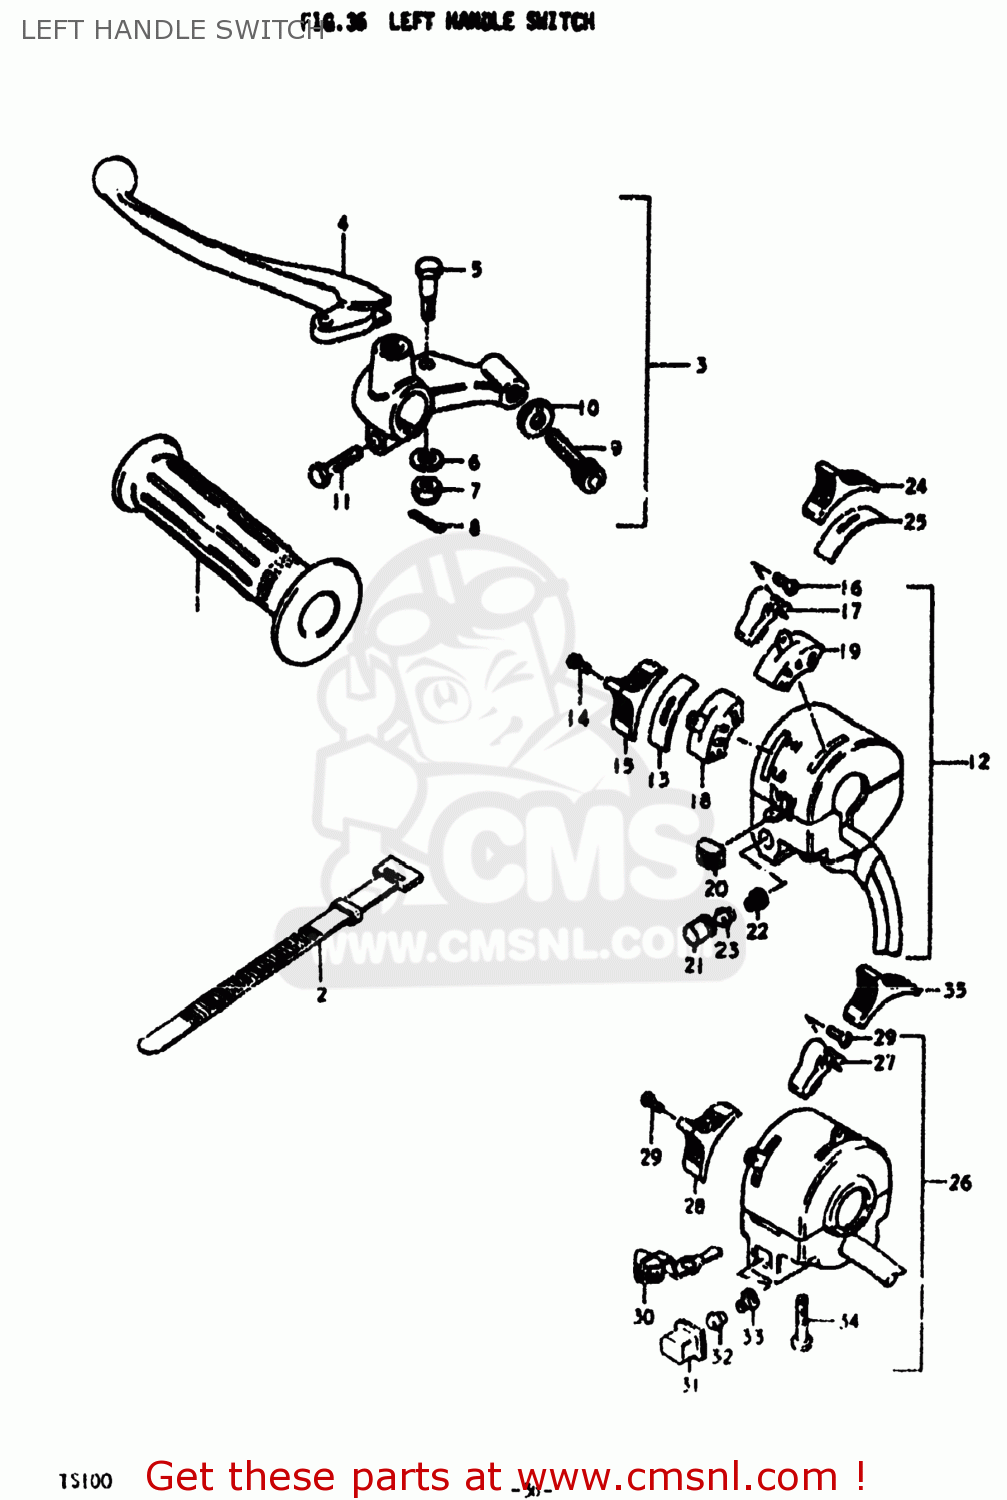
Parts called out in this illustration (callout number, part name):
1	GRIP,L
2	CLAMP(L:120)
3	LEVER ASSEMBLY
4	LEVER,CLUTCH
5	BOLT,LEVER
6	LOCK WASHER
7	NUT 6MM
8	COTTER PIN
9	ADJUSTER,CABLE
10	NUT,CABLE ADJUSTER
11	BOLT
12	SWITCH ASSEMBLY,HANDLE,LEFT
13	PLATE,DIMMER KNOB
14	SCREW, DIMMER
15	KNOB,HANDLE SWITCH,UPPER
16	SCREW
17	KNOB
18	SLIDING BLOCK, DIMMER SWITCH
20	KNOB,HANDLE SWITCH
21	BUTTON, HORN
22	SPRING,BUTTON
23	PLATE,HORN BUTTON
24	KNOB,HANDLE SWITCH
25	PLATE,LIGHTING KNOB
26	SWITCH ASSEMBLY,HANDLE,LEFT
27	KNOB,STOP
28	KNOB,DIMMER SWITCH
29	SCREW
30	KNOB,TURNSIGNAL
31	BUTTON,HORN
32	CONTACT
33	SPRING
34	SCREW
